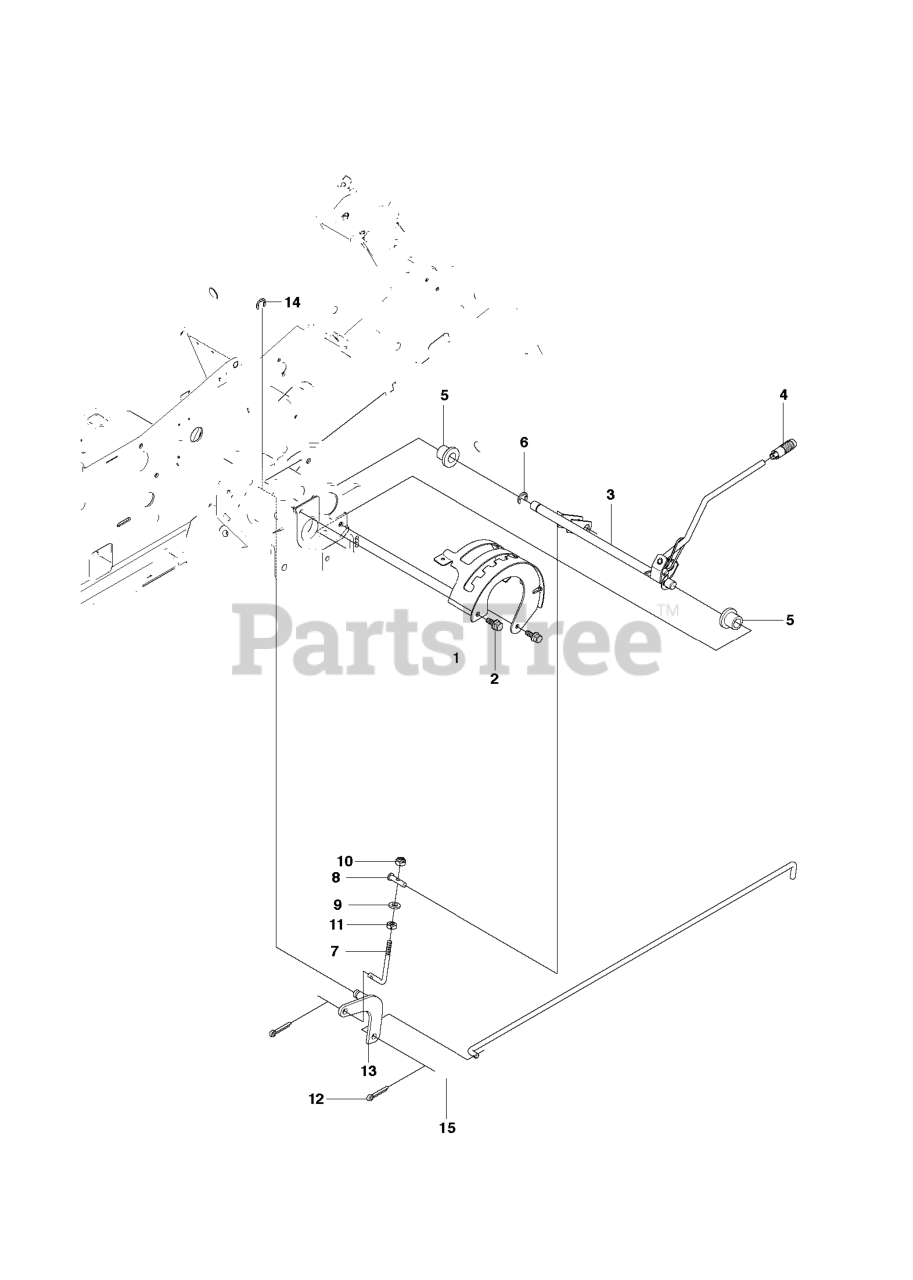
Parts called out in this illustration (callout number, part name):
1	CONTROL PLATE
3	HEIGHT ADJUSTER
4	GEAR STICK KNOB
5	BUSHING
9	WASHER
10	LOCKNUT M8
11	NUT
14	RETAINING RING
15	CONNECTION ROD
